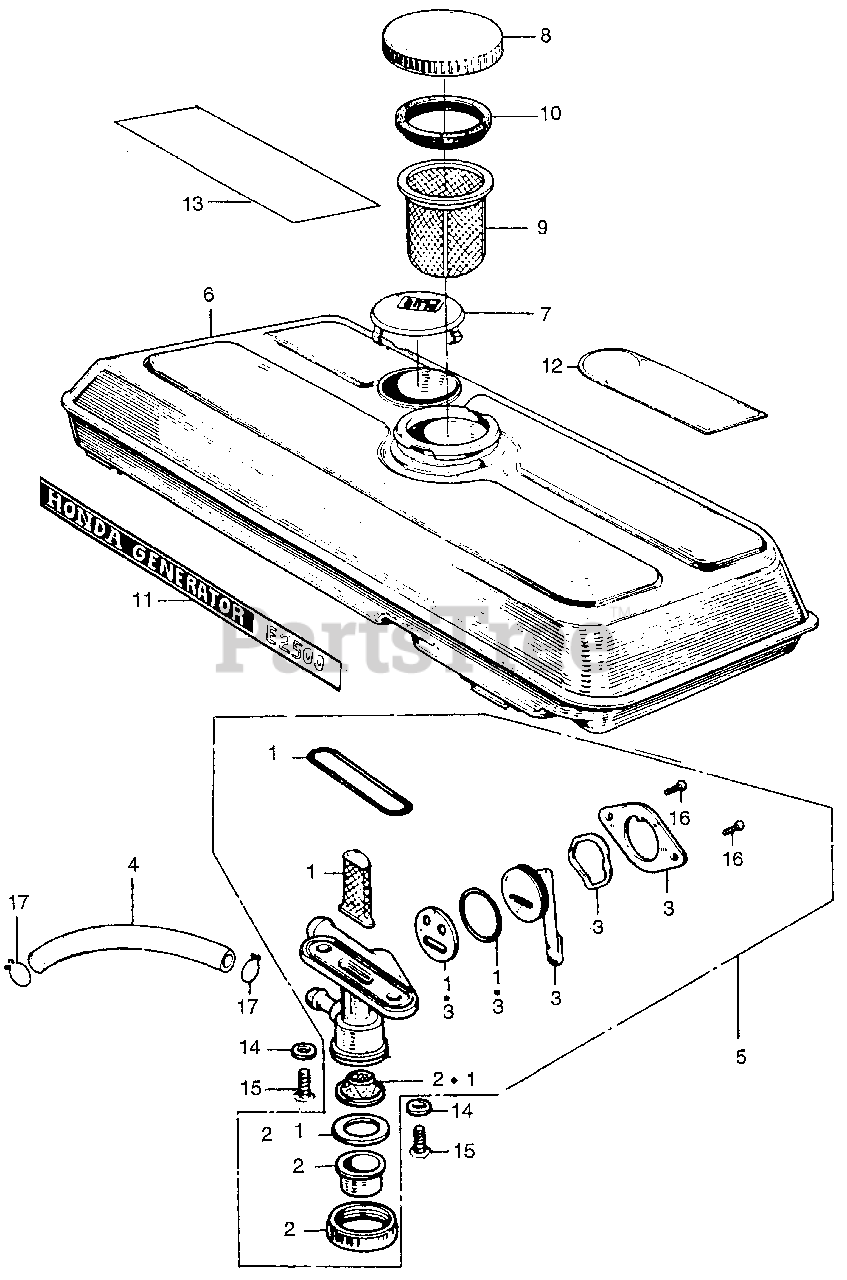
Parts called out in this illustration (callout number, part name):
1	GASKET SET, VALVE
2	CUP SET, STRAINER
3	LEVER SET, VALVE (NOT AVAILABLE)
4	TUBE, FUEL (NOT AVAILABLE)
5	PETCOCK ASSY. (NOT AVAILABLE)
6	TANK, FUEL *NH31* (MCKINLEY WHITE) (NOT AVAILABLE)
8	CAP, FUEL TANK (NOT AVAILABLE)
9	FILTER, FUEL
10	GASKET, FUEL FILTER (NOT AVAILABLE)
12	MARK A, CAUTION
13	MARK, CAUTION (CO)(ENGLISH/FRENCH)(SPANISH)
14	GASKET, FIBER (6MM)
15	SCREW, PAN (6X16)
16	SCREW, PAN (3X8)
